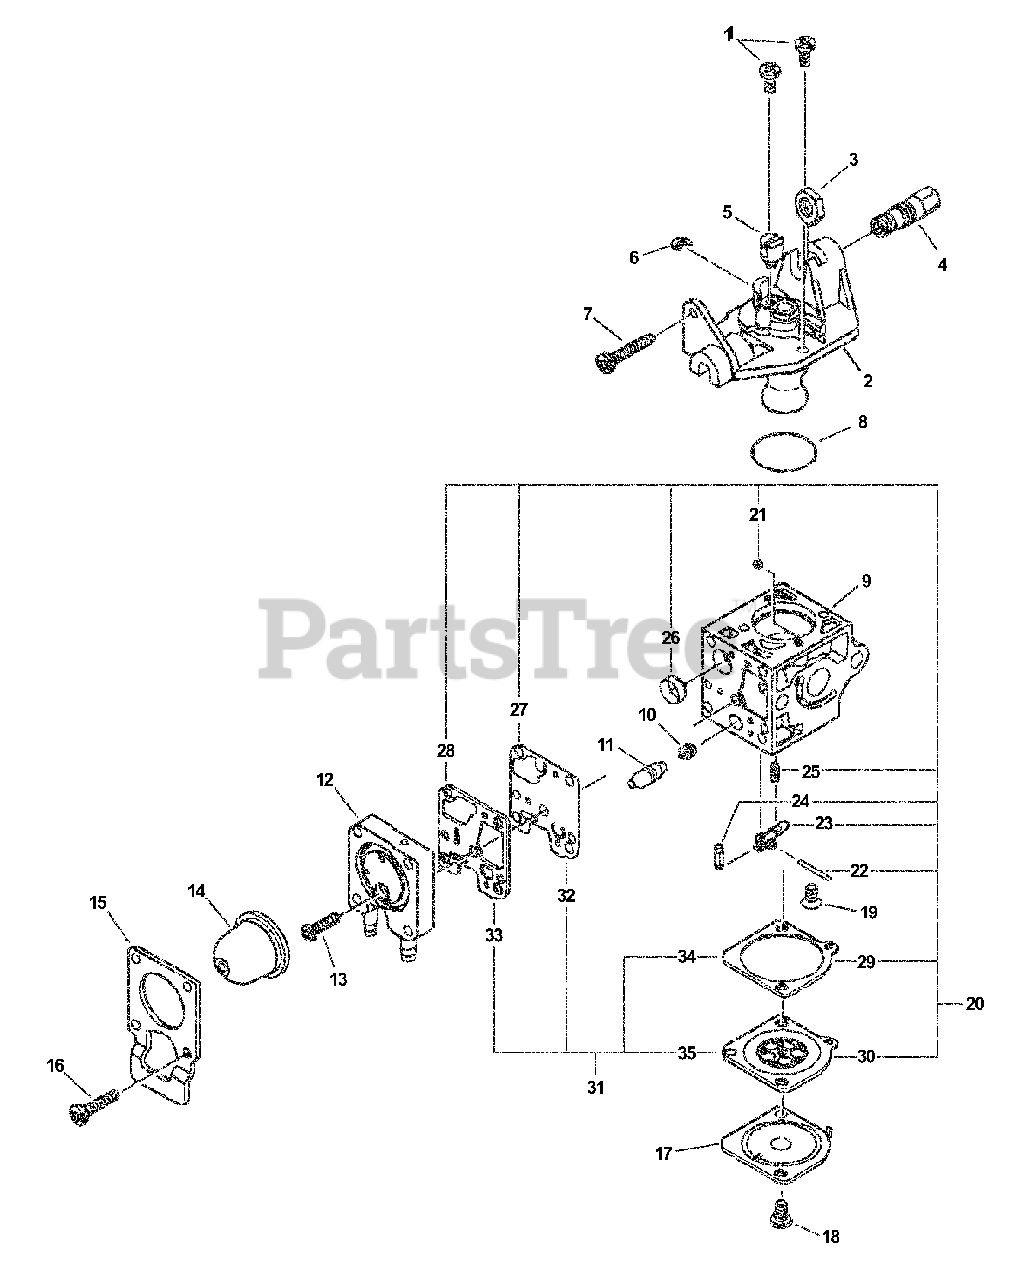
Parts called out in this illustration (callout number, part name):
2	ROTOR COVER ASSY
4	ADJUSTER, THROTTLE CABLE
7	SCREW, IDLE ADJUST
9	BODY, CARBURETOR
10	JET, MAIN
11	PLUG KIT
12	BASE, PURGE
14	BULB, PURGE
15	RETAINER, PURGE BULB
16	SCREW, PURGE BULB RETAINER
17	COVER, METERING DIAPHRAGM
20	REBUILD KIT
21	GUIDE, ROLLER
22	PIN, METERING LEVER
23	LEVER, METERING
24	VALVE, INLET NEEDLE
25	SPRING, METERING LEVER
26	STRAINER
27	DIAPHRAGM, PUMP
28	GASKET, PUMP
29	GASKET, METERING
30	DIAPHRAGM, METERING
31	GASKET / DIAPHRAGM KIT
32	DIAPHRAGM, PUMP
33	GASKET, PUMP
34	GASKET, METERING
35	DIAPHRAGM, METERING
